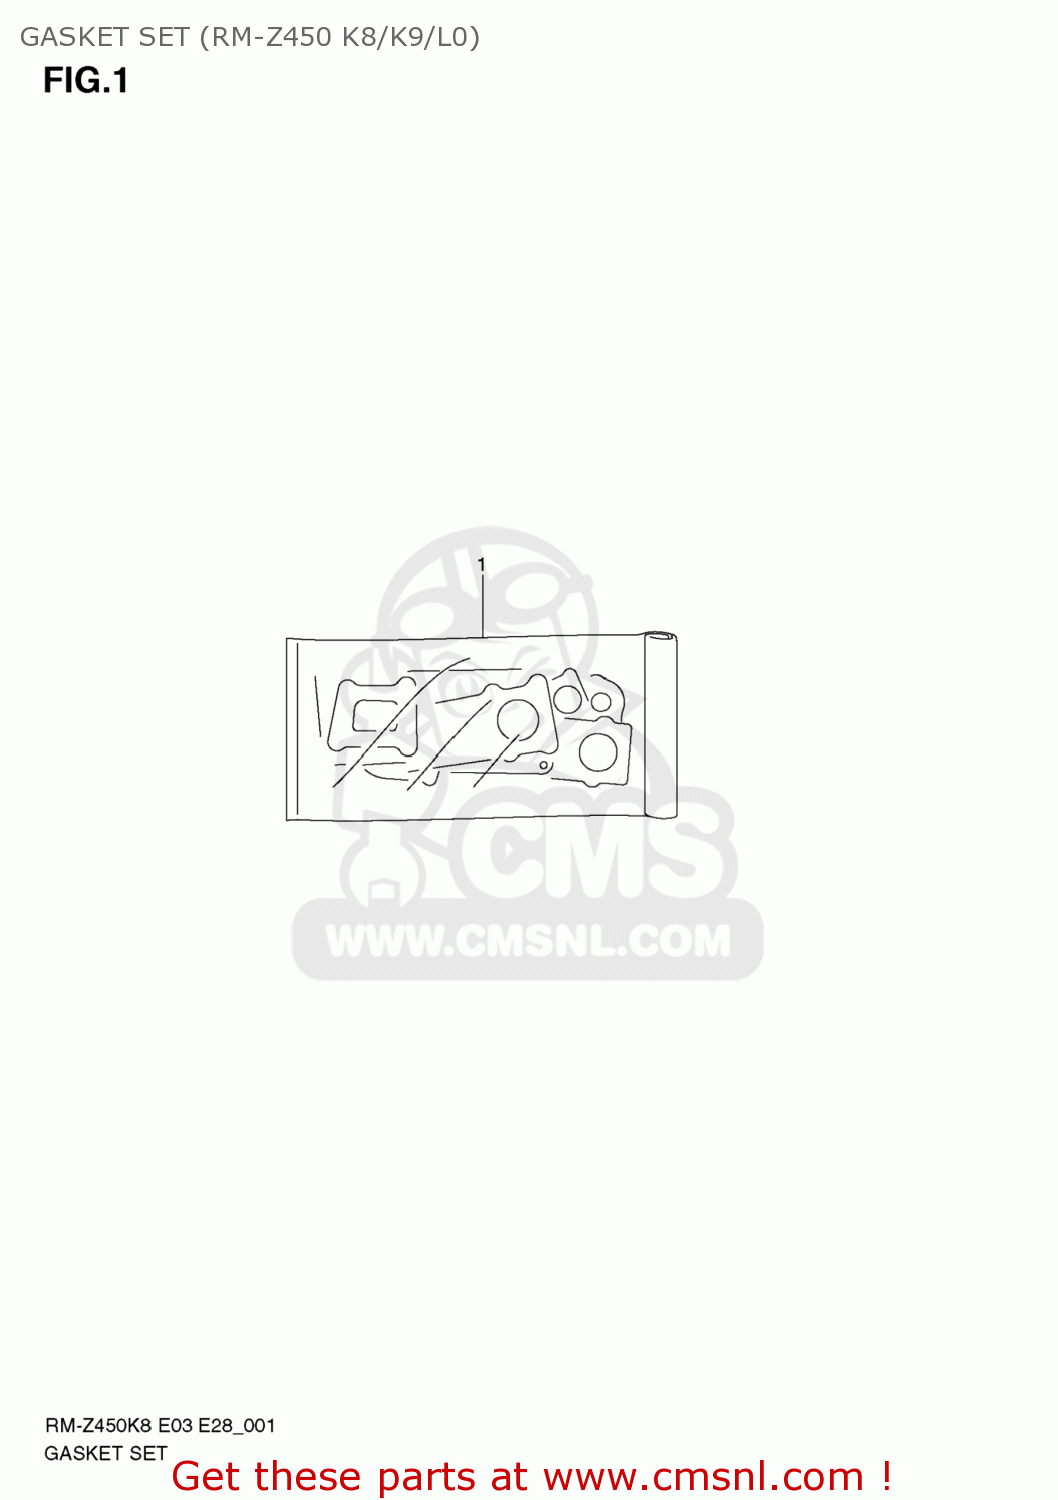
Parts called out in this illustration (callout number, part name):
1	GASKET SET (NAS)
2	GASKET,CYLINDER HEAD (NAS)
3	GASKET,CYL HEAD COVER (NAS)
4	GASKET,CYLINDER (NAS)
5	GASKET,CRANKCASE (NAS)
6	GASKET,CLUTCH COVER (NAS)
7	GASKET,MAGNETO COVER (NAS)
8	GASKET,CLUTCH COVER OUTER (NAS)
9	GASKET,TENSIONER ADJUSTER (NAS)
10	GASKET,EXHAUST PIPE (NAS)
11	O RING,WATER PUMP CASE
